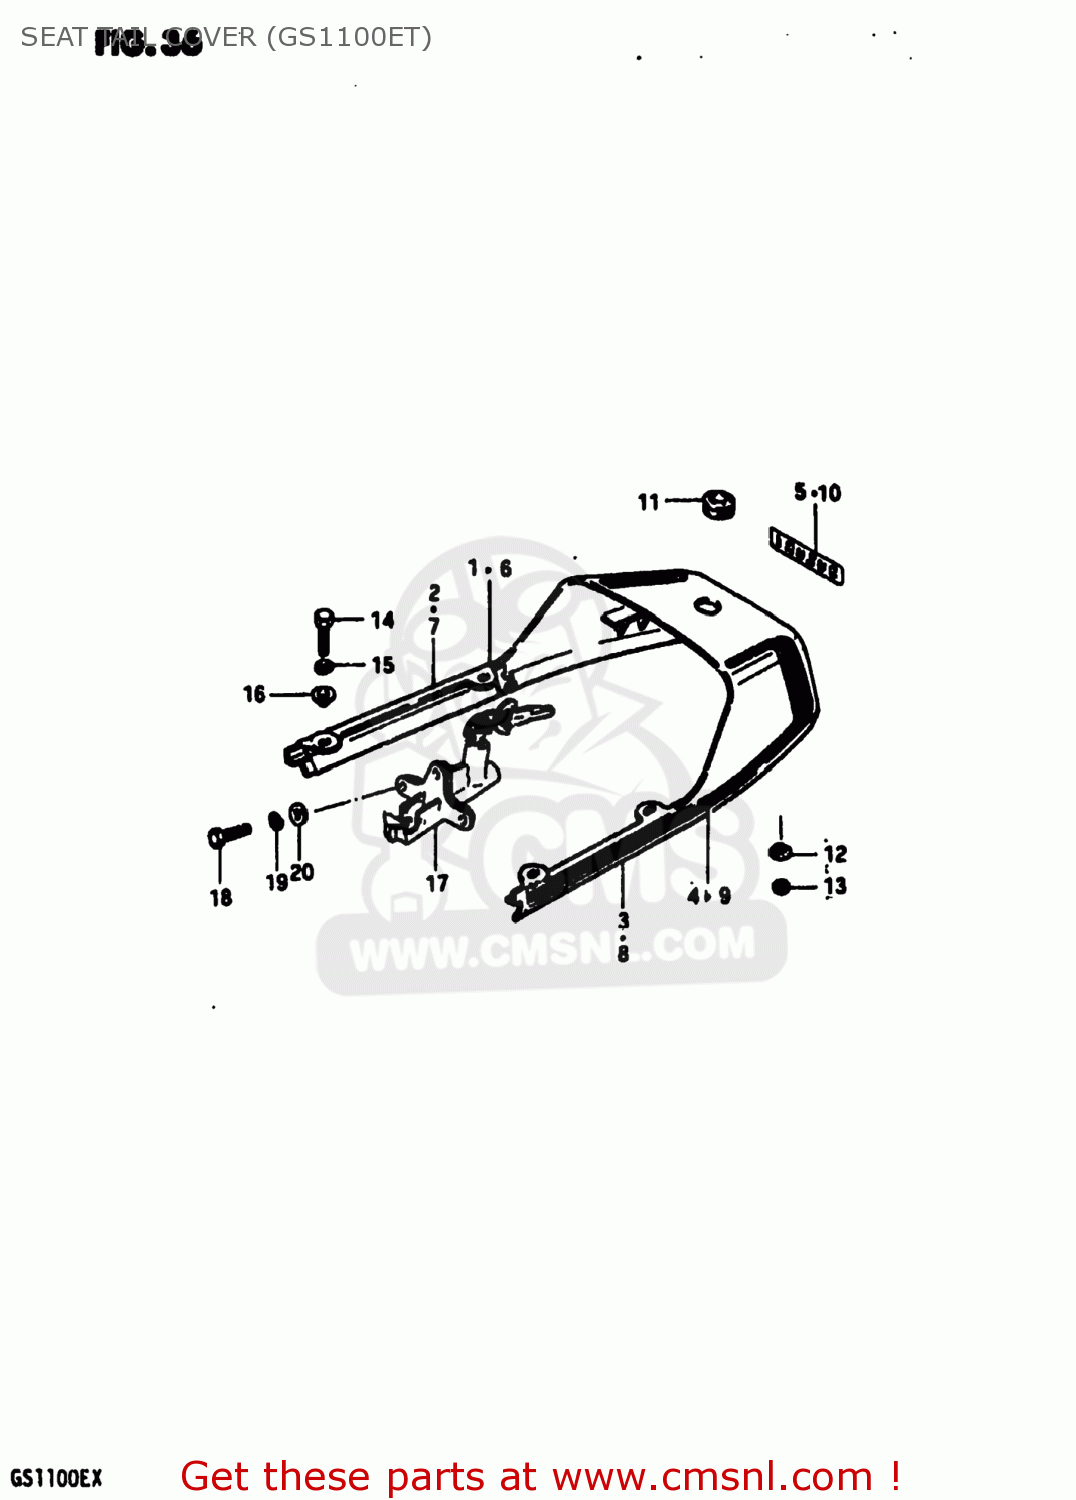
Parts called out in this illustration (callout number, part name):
1	COVER,SEAT TAIL
2	MOLDING,SEAT
3	MOLDING,SEAT
5	EMBLEM,SEAT TAIL COVER
6	COVER,SEAT TAIL
7	MOLDING,SEAT
8	MOLDING,SEAT
10	EMBLEM (GOLD/BLACK)
11	GROMMET,SEAT LOCK HOLE
12	WASHER
13	NUT 6MM
14	BOLT
15	LOCK WASHER
16	WASHER
17	LOCK SET
18	BOLT
19	LOCK WASHER
20	WASHER 6MM
